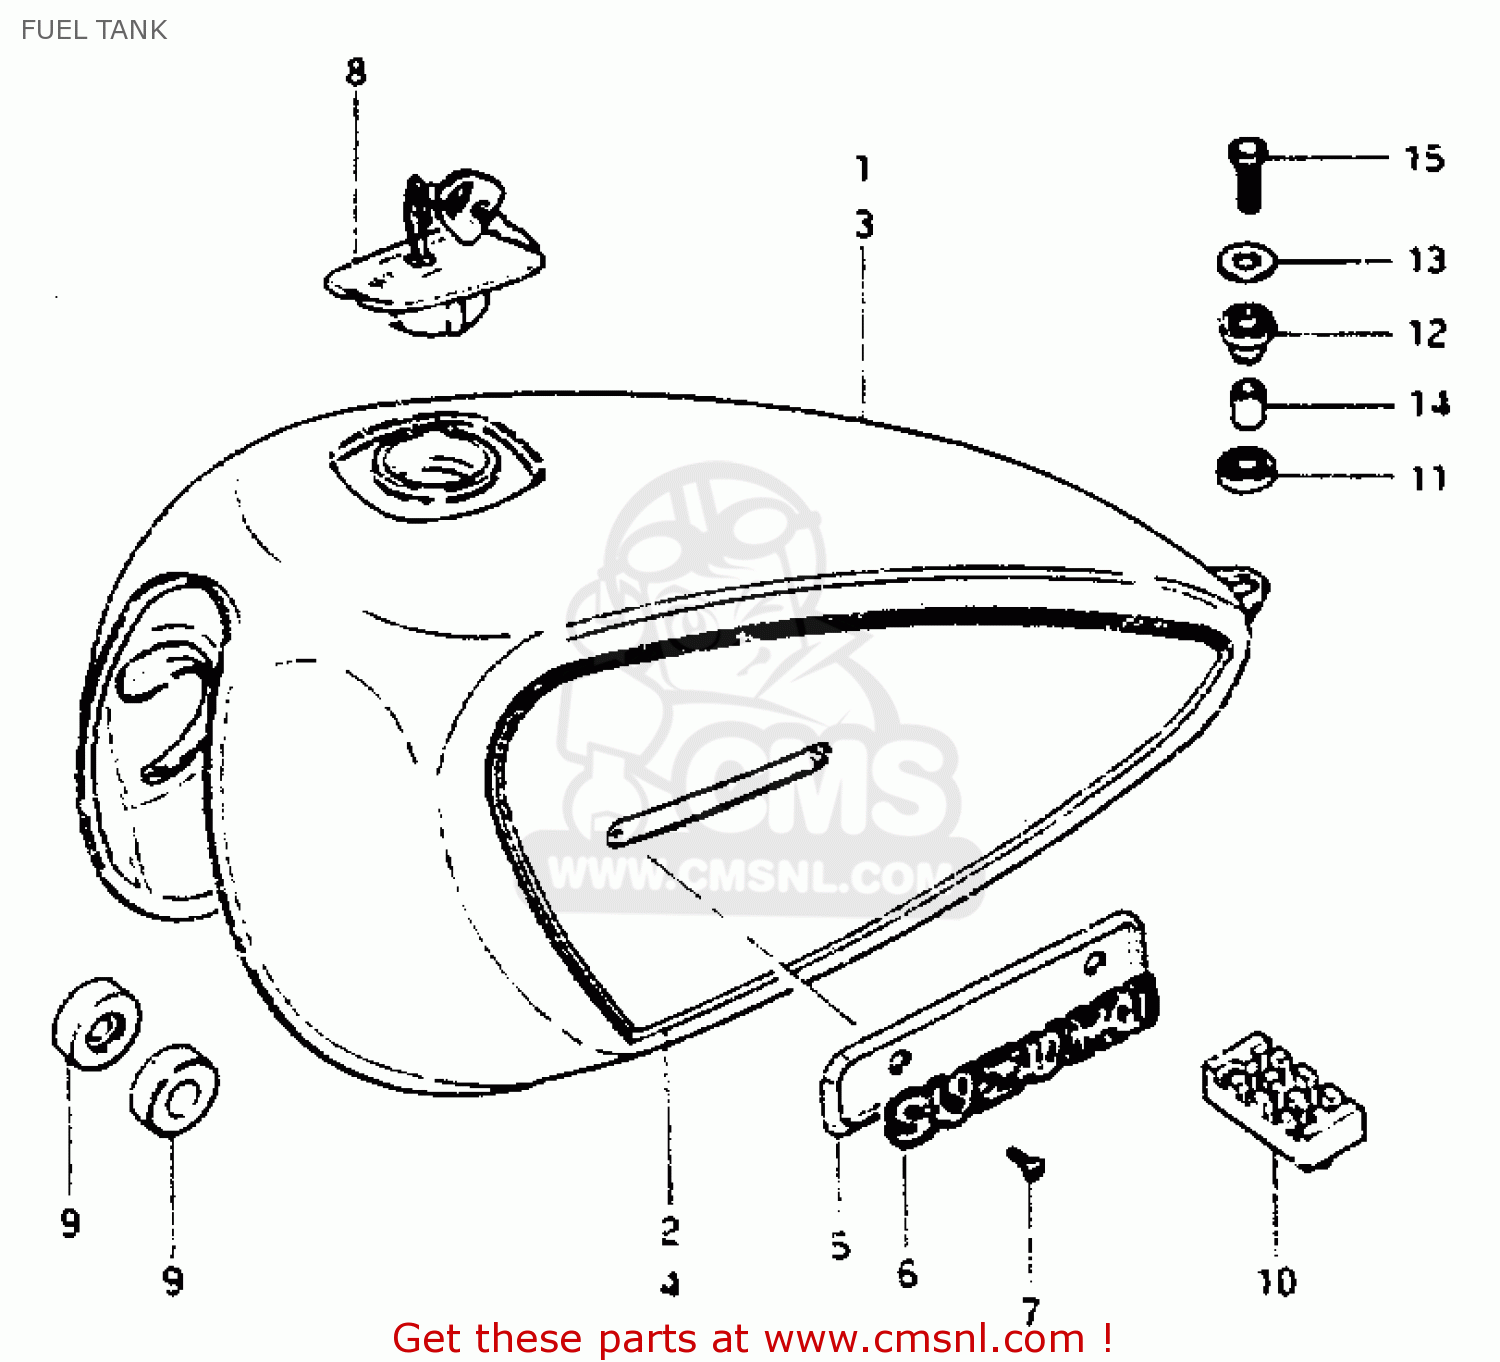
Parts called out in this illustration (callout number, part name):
1	TANK ASSEMBLY,FUEL
2	TAPE SET,FUEL TANK
3	TANK ASSEMBLY,FUEL
4	TAPE SET,FUEL TANK
6	EMBLEM,FUEL TANK
7	SCREW 3X6
8	CAP SET,FUEL TANK
9	CUSHION
10	CUSHION,FUEL TANK CTR
11	CUSHION
12	CUSHION
13	WASHER (6.5X24X1.6)
14	SPACER
15	BOLT
